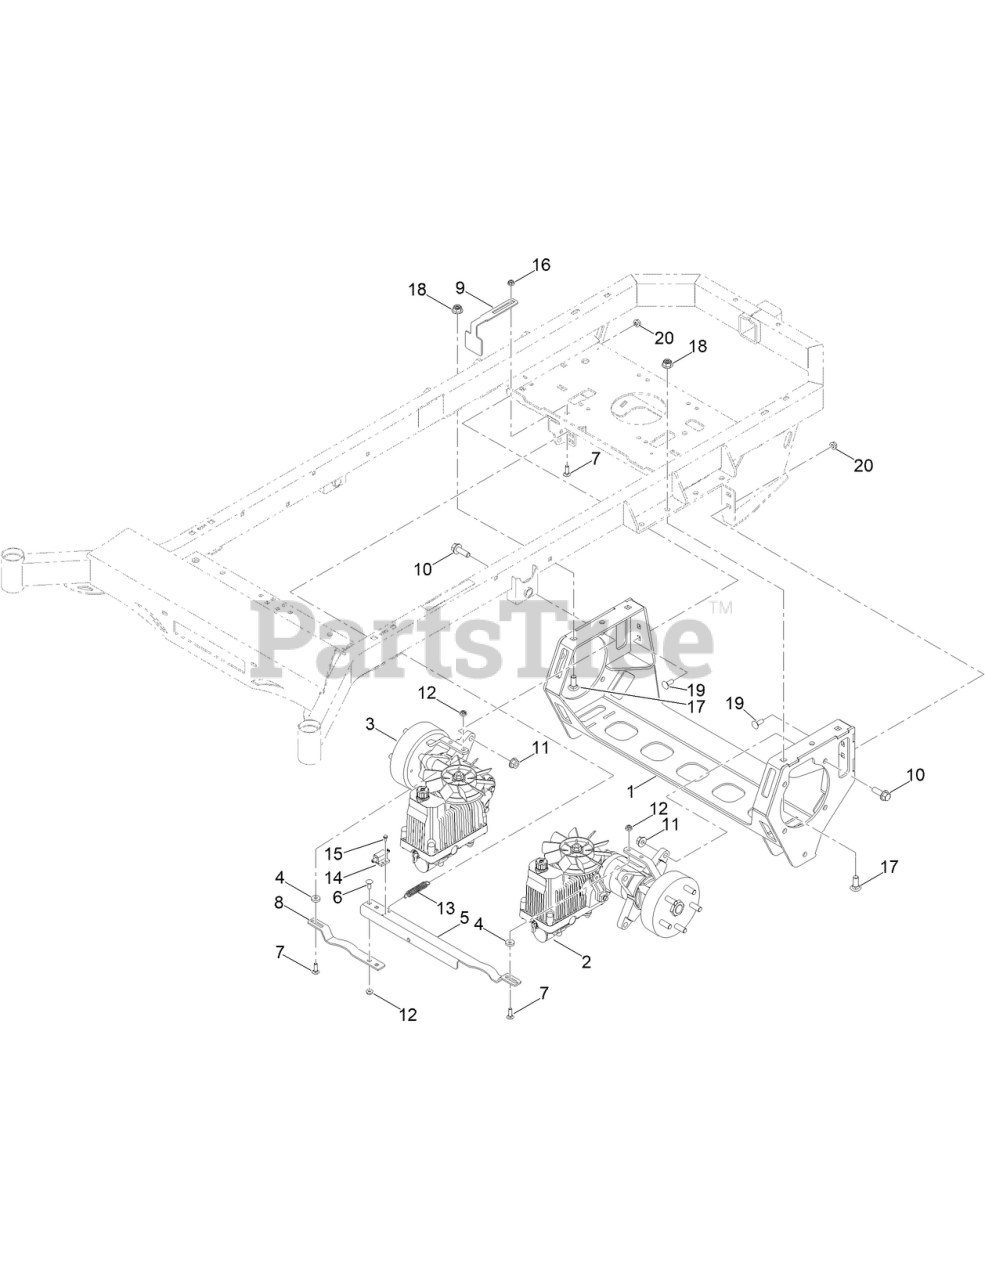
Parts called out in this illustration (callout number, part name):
1	HYDRO FRAME ASM
2	HTJ12 PARKER LT SIDE HYDROSTATIC TRANSM
3	HTJ12 PARKER RT SIDE HYDROSTATIC TRANSM
4	.312 ID X .875OD X .1875 THK F/W NYL
5	MWR PARK BRAKE BRKT LT PAINT
6	BOLT-CARR
7	BOLT-CARR
8	MWR PARK BRAKE BRKT RT PAINT
9	STAND TRANS BRAKE INTERLOCK BRKT PAINT
10	SCREW-HHF
11	NUT-HHF
12	5/16-18 NYLON INSERT FLANGE L/NUT ZC
13	MWR BRAKE PEDAL RELEASE SPRING
14	NO PLUNGER LIMIT SWITCH
15	8-32 X 1/2 IND. HWH SLOT TYPE F TCS ZINC
17	SCREW-CARR
18	1/2-13 HEX FLANGE 2-WAY REV CNTR L/NYZ
19	3/8-16 X 1 CARRIAGE BOLT YZ GR.8
